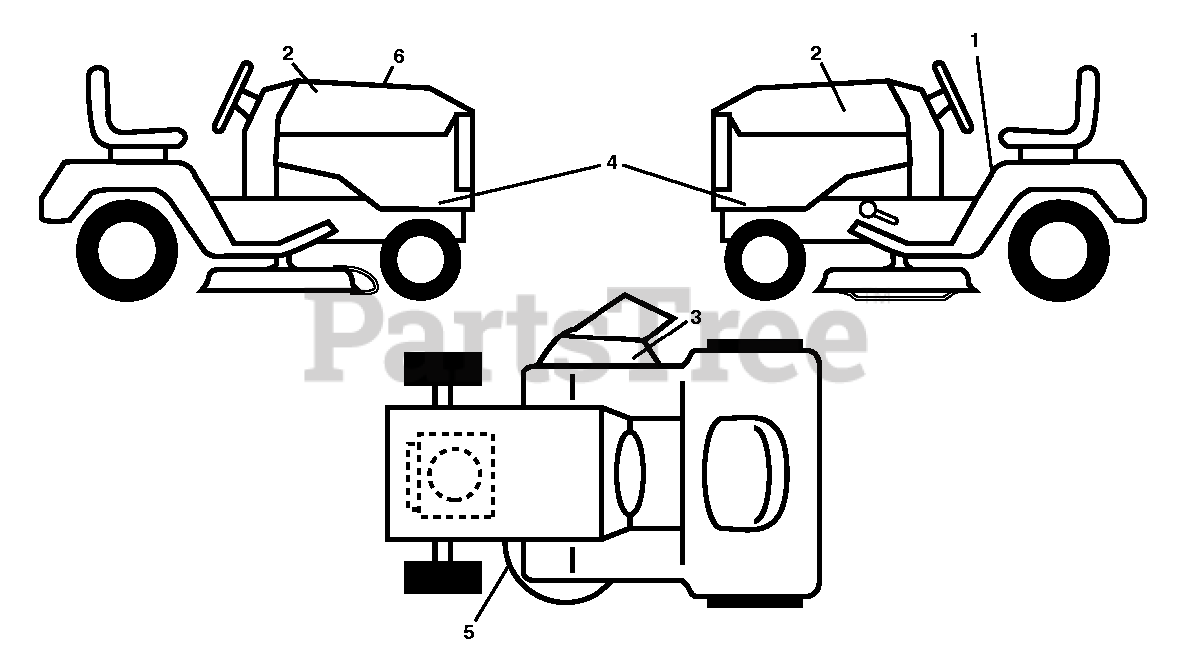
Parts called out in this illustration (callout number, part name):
1	DECAL.WARNING.2007.ENG/FR
2	DECAL.WB.178MM.15.HUSQ.NEWBRAN
3	DECAL, DECK DEFLECTOR, WARNING
4	DECAL TRACTOR SIDE PANEL DECAL
5	DECAL.V-BELT.SCH.42/46"MEC/ELE
